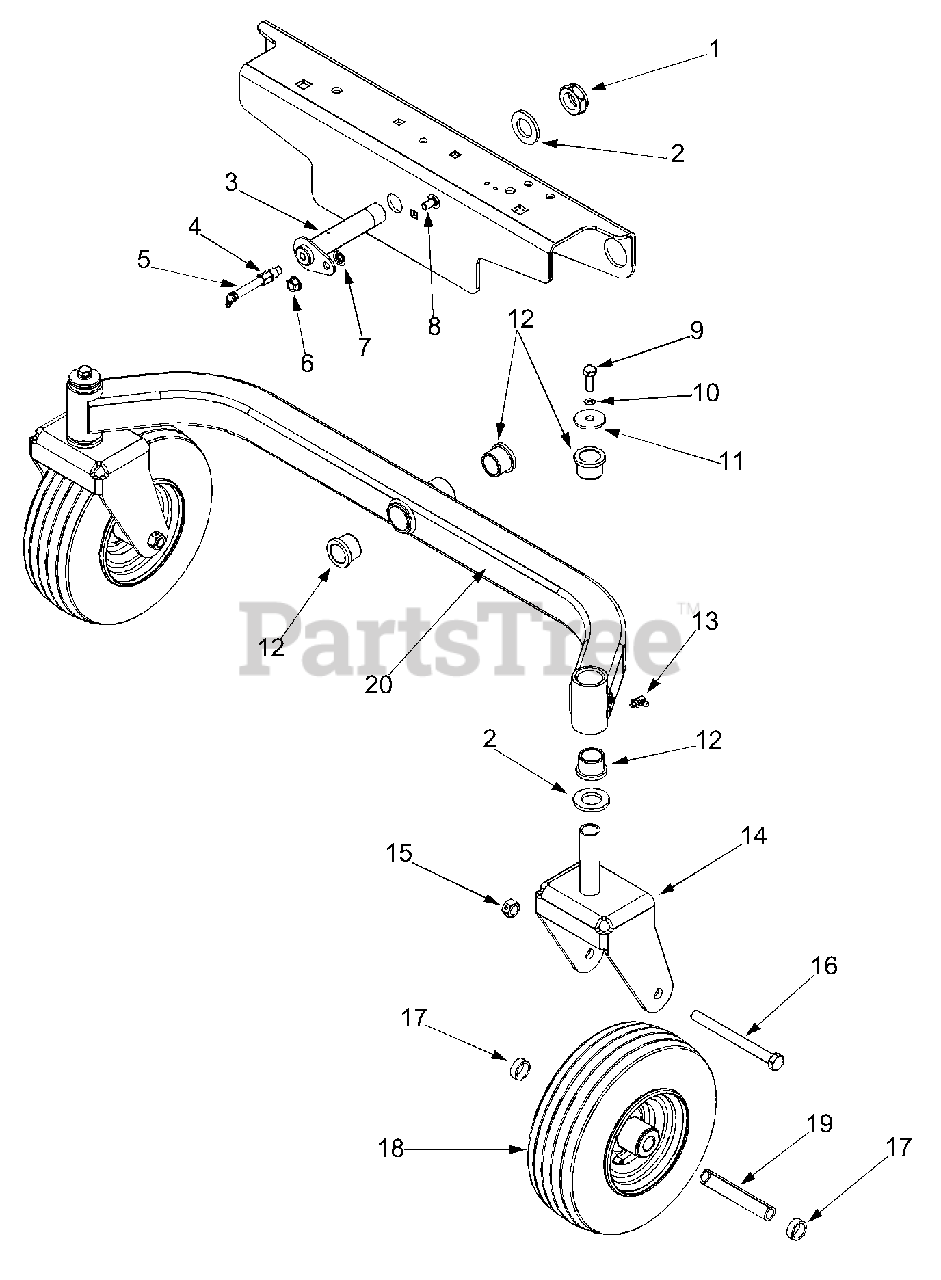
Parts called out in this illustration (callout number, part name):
1	Hex Lock Nut, 1.0-14
2	Flat Washer
3	Pin Ass'y, Pivot
4	Adapter, 1/8 NPTF x 1/8 NPTF
5	Grease Fitting, 65° w/Extension
6	Hex Flange Lock Nut, 3/8-16
7	Push Nut, 3/8 ID
8	Carriage Bolt, 3/8-16 x .75
9	Hex Cap Screw, 3/8-16 x 1.0
10	Lock Washer 3/8
11	Flat Washer 3/8 x 1.5
12	Flange Bearing 1.0 ID
13	Grease Fitting
15	Hex Center Lock Nut 1/2-20
16	Hex Cap Screw, 1/2-20 x 5.5
17	Spacer, .79 ID x .347 Lg
18	Wheel Comp 11.0 x 4.0 x 5.0
19	Wheel Spacer
